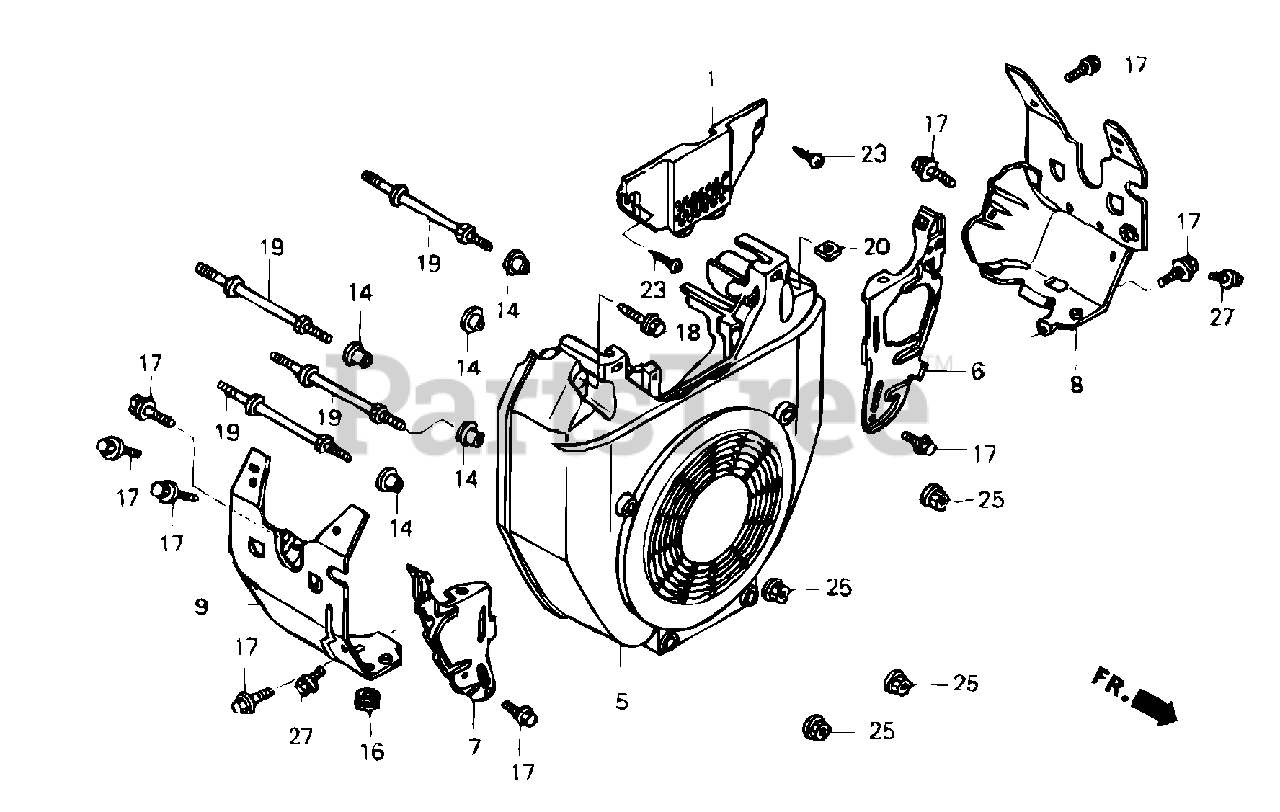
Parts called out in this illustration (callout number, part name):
1	Cover, Fuel Pump
5	Cover, Fan (Bright Red)
6	Plate, R. Side
7	Plate, L. Side
9	Shroud, L
14	Collar B, Taillight
16	Rubber, Rr. Fender Cushion
17	Bolt, Flange (6x12) (Ct200)
18	Bolt, Flange (6x23)
19	Bolt, Stud (6x71)
20	Nut, Square (5mm)
23	Screw, Tapping (5x20)
25	Nut, Flange (6mm)
27	Bolt, Flange (6x8)
